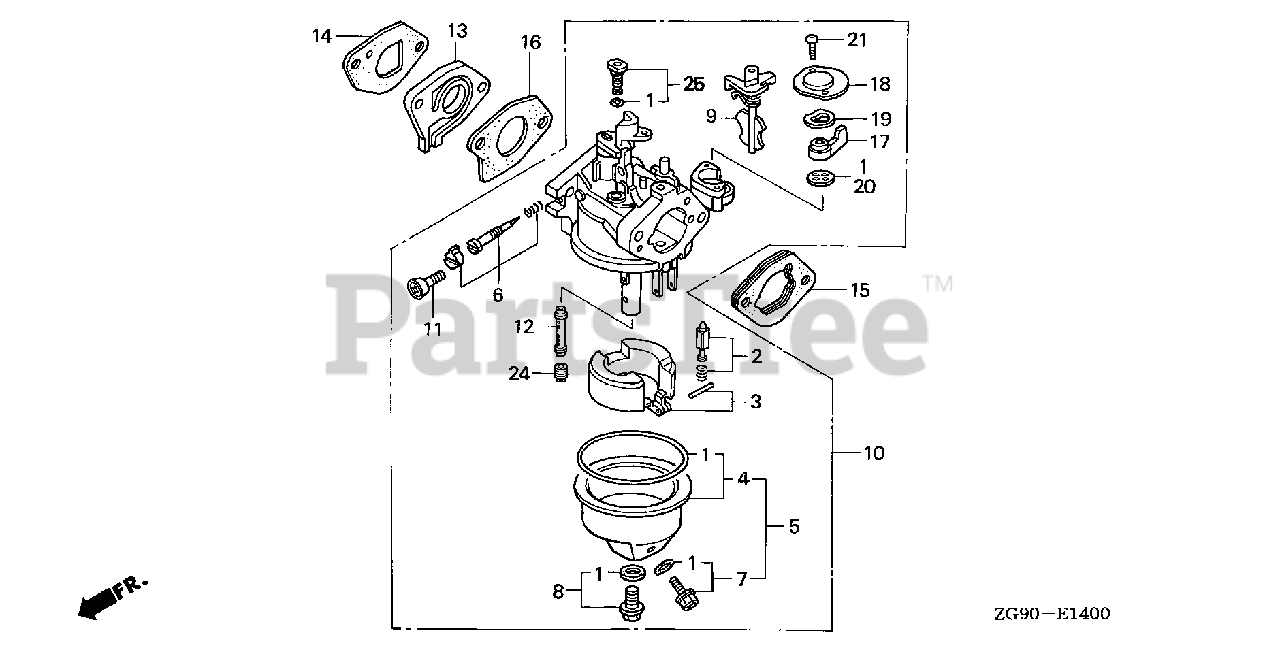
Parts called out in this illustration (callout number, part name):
1	GASKET SET (CARBURETOR NO.)
2	VALVE SET, FLOAT (CARBURETOR NO.)
3	FLOAT SET (CARBURETOR NO.)
4	CHAMBER SET, FLOAT (CARBURETOR NO.)
5	CHAMBER SET, FLOAT (CARBURETOR NO.)
6	SCREW SET, PILOT (CARBURETOR NO.)
7	SCREW SET, DRAIN (CARBURETOR NO.)
8	SCREW SET (CARBURETOR NO.)
8	SCREW SET
9	CHOKE SET (CARBURETOR NO.)
10	CARBURETOR ASSY. (BE53A C)
10	CARBURETOR ASSY. (BE53A D)
11	SCREW, THROTTLE STOP (CARBURETOR NO.)
12	NOZZLE, MAIN (CARBURETOR NO.)
13	INSULATOR, CARBURETOR
14	GASKET, CARBURETOR
15	SPACER, CARBURETOR
16	GASKET, CARBURETOR
17	LEVER, PETCOCK (CARBURETOR NO.)
18	PLATE, LEVER SETTING (CARBURETOR NO.)
19	SPRING, PETCOCK LEVER (CARBURETOR NO.)
20	GASKET, PETCOCK (CARBURETOR NO.)
21	SCREW, PAN (3X6)
24	JET, MAIN (#55) Use up to Engine SN BE53A A.
24	JET, MAIN (#58) Use up to Engine SN BE53A A.
24	JET, MAIN (#60) (CARBURETOR NO.)
24	JET, MAIN (#52) Use from Engine SN BE53A B.
24	JET, MAIN (#55) Use from Engine SN BE53A B.
24	JET, MAIN (#58) (CARBURETOR NO.)
24	JET, MAIN (#58)
25	JET SET, PILOT (#38) (CARBURETOR NO.)
25	JET SET, PILOT (#40) (CARBURETOR NO.)
